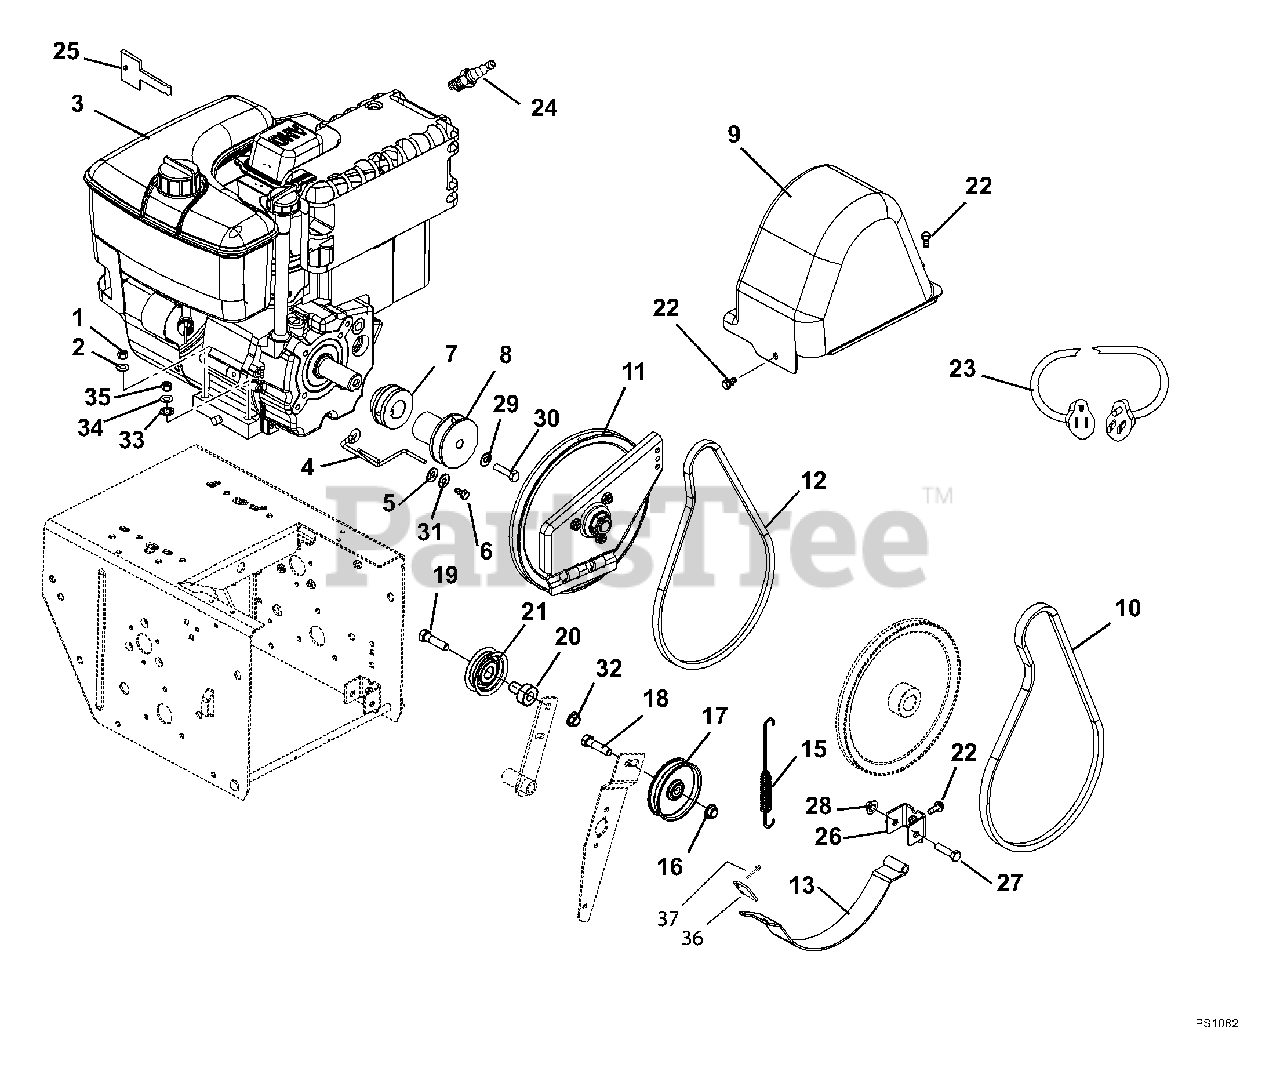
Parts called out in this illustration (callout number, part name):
1	@NUT-HEX .31-18 YWZC
2	WSHR-LK .312X.097 HVY YWZC
3	ENGINE,9.25HP TEC LH318SA 120V
4	FINGER, BELT
5	@WSHR-FL-STL.38X.875X.083 YWZC
6	BLT-HEX .31-24X.75 YWZC GR5
7	SHEAVE, DRIVE
8	SHEAVE, ATTACHMENT
9	COVER, BELT
10	V-BELT, 4L-RAW EDGE
11	PLATE, SWING-ASSY
12	V-BELT, 3L-RAW EDGE
13	ARM, BRAKE-ATTACHMENT
15	SG-TENS .056X.60X4.40
16	@NUT-LK-TOP-FLG .38-16 YWZC
17	IDLER, FLAT-3.00
18	@BLT-HEX .38-16X1.50 GR5 YWZC
19	@BLT-HEX .31-18X1.25 GR5 YWZC
20	SPCR, BRG .315X.50X.688X.281
21	IDLER
22	@SCR-TAP .25-20X.50 HWH TR YWZ
23	CORD, ELECTRIC START CORD 120V
24	PLUG, SPARK
25	KEY, PUSH/PULL - TECUMSEH
26	PIVOT, BRAKE
27	@BLT-HEX .31-18X2.00 GR5 YWZC
28	@NUT-LK-TOP-FLG .31-18 YWZC
29	@WSHR-LK .38X.094 REG YWZC
30	BLT-HEX .38-24X2.0 YWZC
31	WSHR-LK .312X.097 HVY YWZC
32	@NUT-LK-TOP-FLG .31-18 YWZC
33	WSHR-LOCK INT .31 YWZC
34	@WSHR-FL-STL.344X.688X.065YWZC
35	@NUT-LK-CTR .31-18 YWZC
36	PAD, BRAKE
37	RVT-POP .187 YZ
